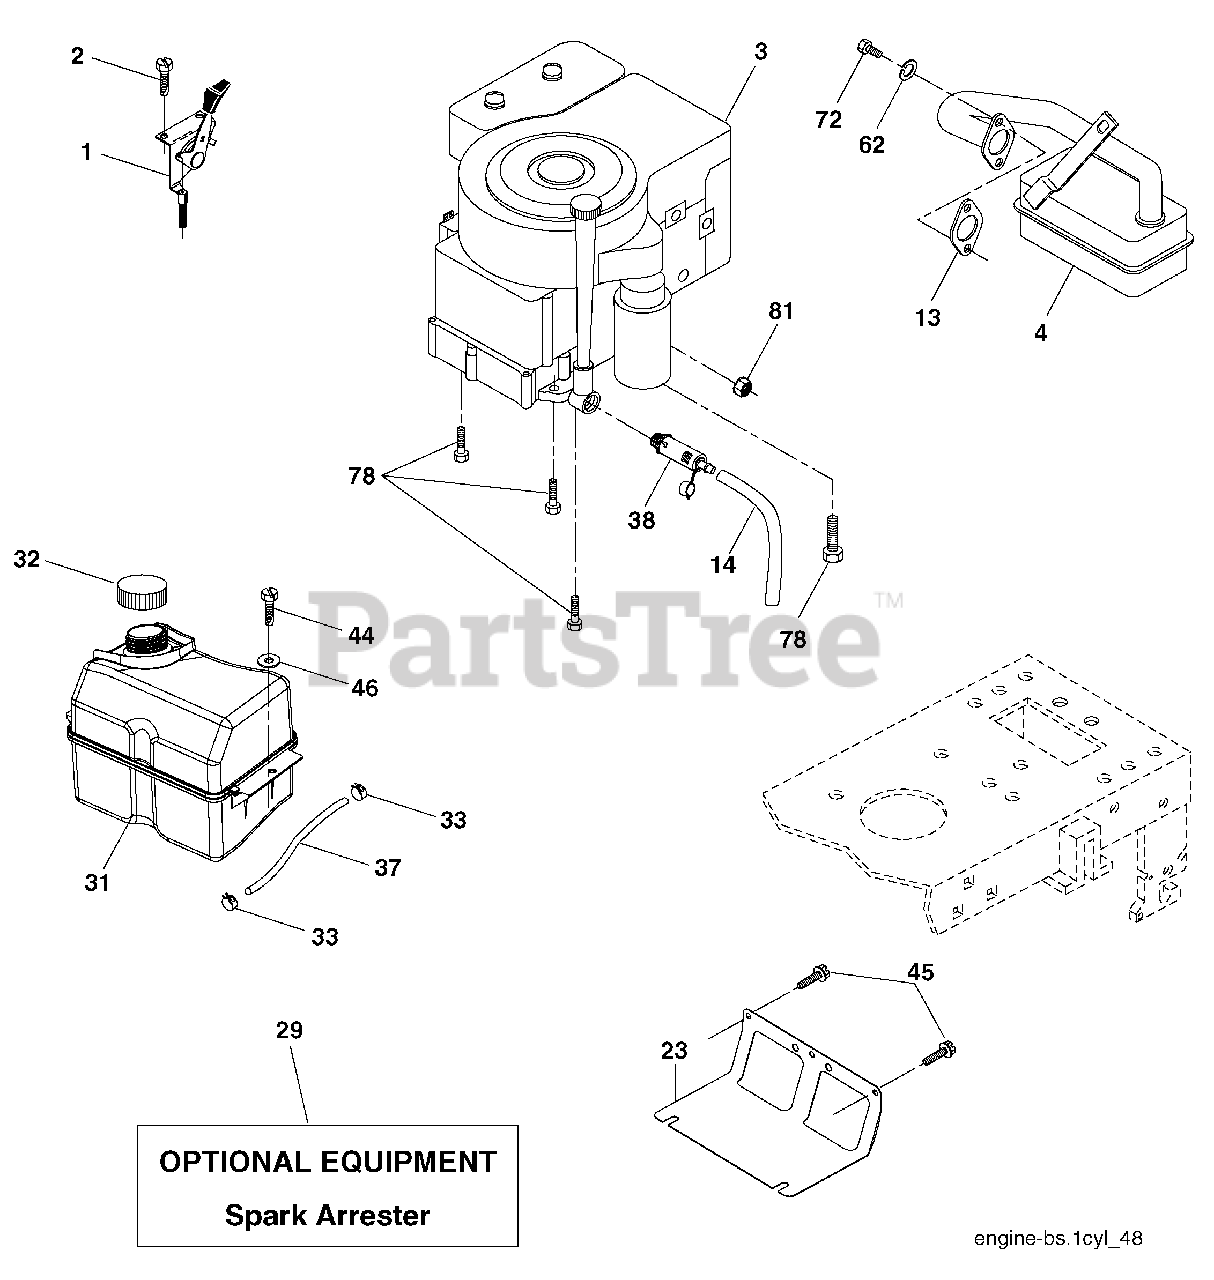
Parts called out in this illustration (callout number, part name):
1	Control Throt/Ck
2	Screw Hex Thd Cut 1/4-20 x 1/2
13	Gasket Muffl er
14	Tube Drain Oil Easy
23	Shield Brn/Dbr Guard
29	Kit Spark Arrestor (Flat Scrn)
31	Tank Fuel
32	Cap Asm Fuel Top
33	Clamp Hose Blk
38	Plug Drain Oil Easy
44	Screw Hexwsh thdrol 1/4-20 x 3/4
45	Screw Hexwsh Thdr 3/8-16 x 3/4
46	Washer 9/32 x 7/8 x 16 Ga.
72	Screw Socket Hd 5/16-18 x .75
78	Screw 3/8-16 x 1/4
81	Nut Keps Hex 1/4-20 unc
